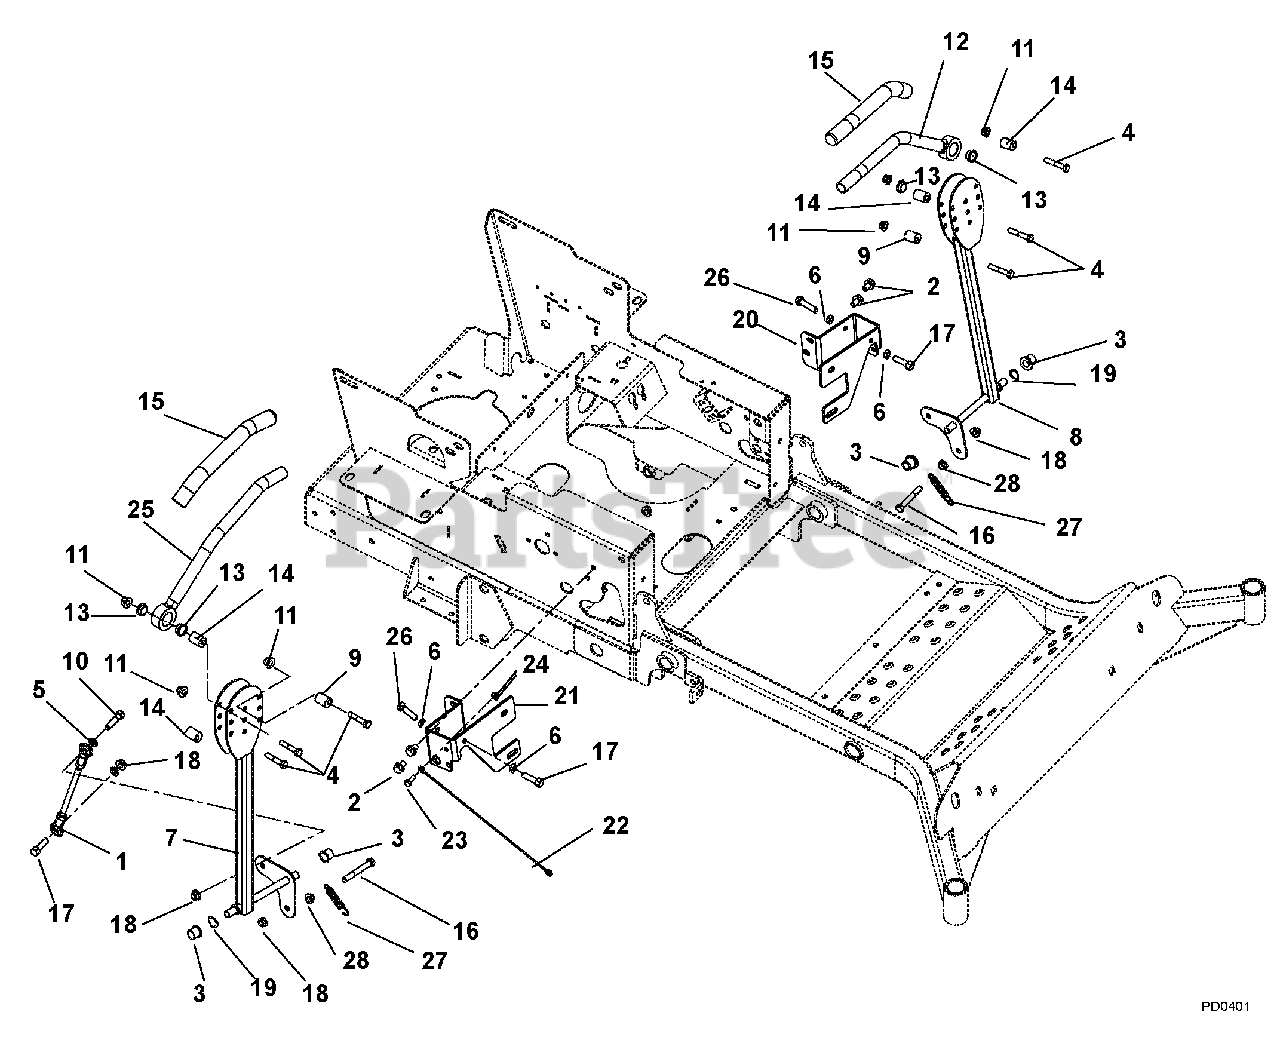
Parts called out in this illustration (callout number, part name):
1	Assembly, Steering Linkage
2	Screw, Tapping .38-16 x .50 Hex Washer Head
3	Bushing, Flange .515 x .750 x .745 x 1.00 Nylon
4	Bolt, Hex .31-18 x 1.75 Grade 5
5	Washer, Locking .38 x .094
6	Nut, Hex Jam .375-16
7	Weldment, Right Hand Control Arm
8	Weldment, Left Hand Control Arm
9	Eccentric
10	Bolt, Hex .38-16 x 1.50 Grade 5
11	Nut, Nyloc Flange .375-16
12	Handle Weldment, Left Hand
13	Bushing, Flange Nylon .762 x 1.48 x .44
15	Grip, Handlebar
16	Bolt, Hex .38-16 x 2.75 Grade 5
17	Bolt, Hex .38-16 x 1.25 Grade 5
18	Nut, Nyloc Flange 3/8-16
19	Wave Washer
20	Stop, Steering, Left Hand
21	Stop, Steering, Right Hand
22	Cable, 12.0 Lanyard, Nylon
23	Bolt, Hex .25-20 x .75 Grade 5
24	Nut, Nyloc Flange .25-20
25	Handle Weldment Right Hand
26	Bolt, Hex .38-16 x .75 Grade 5
27	Spring, External, .061 x .50 x 3.0
28	Nut, Spin Lock Flange .375-16
